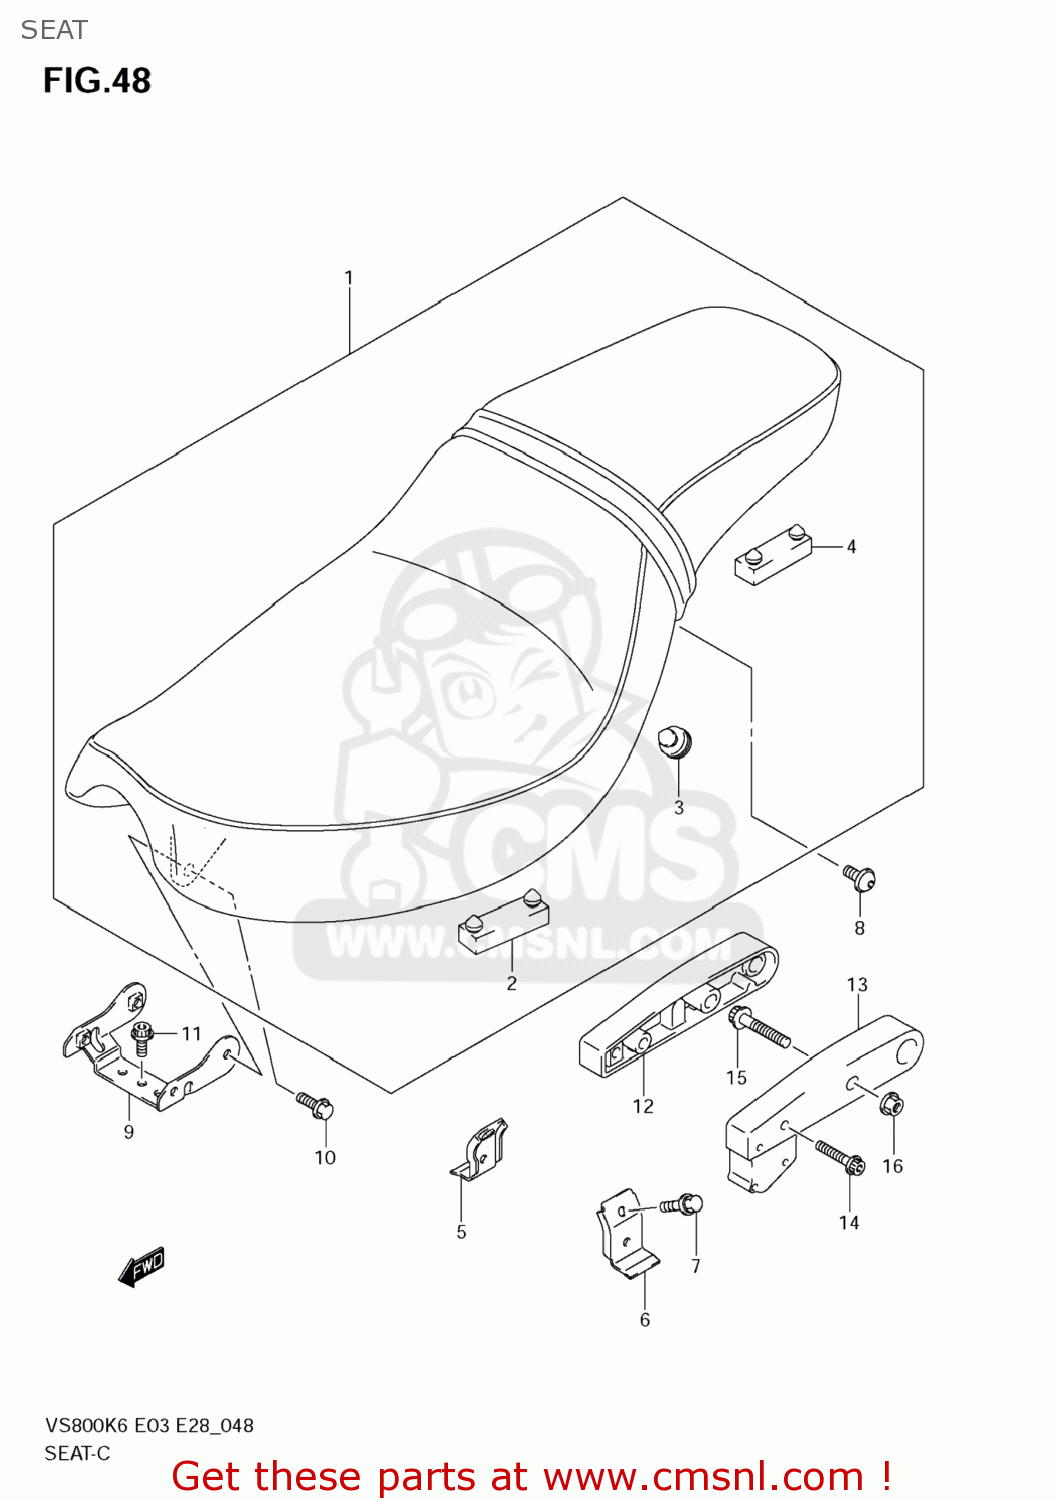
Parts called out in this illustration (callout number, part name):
1	SEAT ASSY
2	CUSHION,SEAT
3	CUSHION(11.5X22X20)
4	CUSHION
5	BRACKET,SEAT CTR,R
6	BRACKET,SEAT CTR,L
7	BOLT
8	BOLT(6X12)
9	BRACKET,SEAT FR
10	BOLT(6X16)
11	BOLT
12	HANDLE,PILLION RIDER,R
13	HANDLE,PILLION RIDER,L
14	BOLT
15	BOLT
16	NUT
